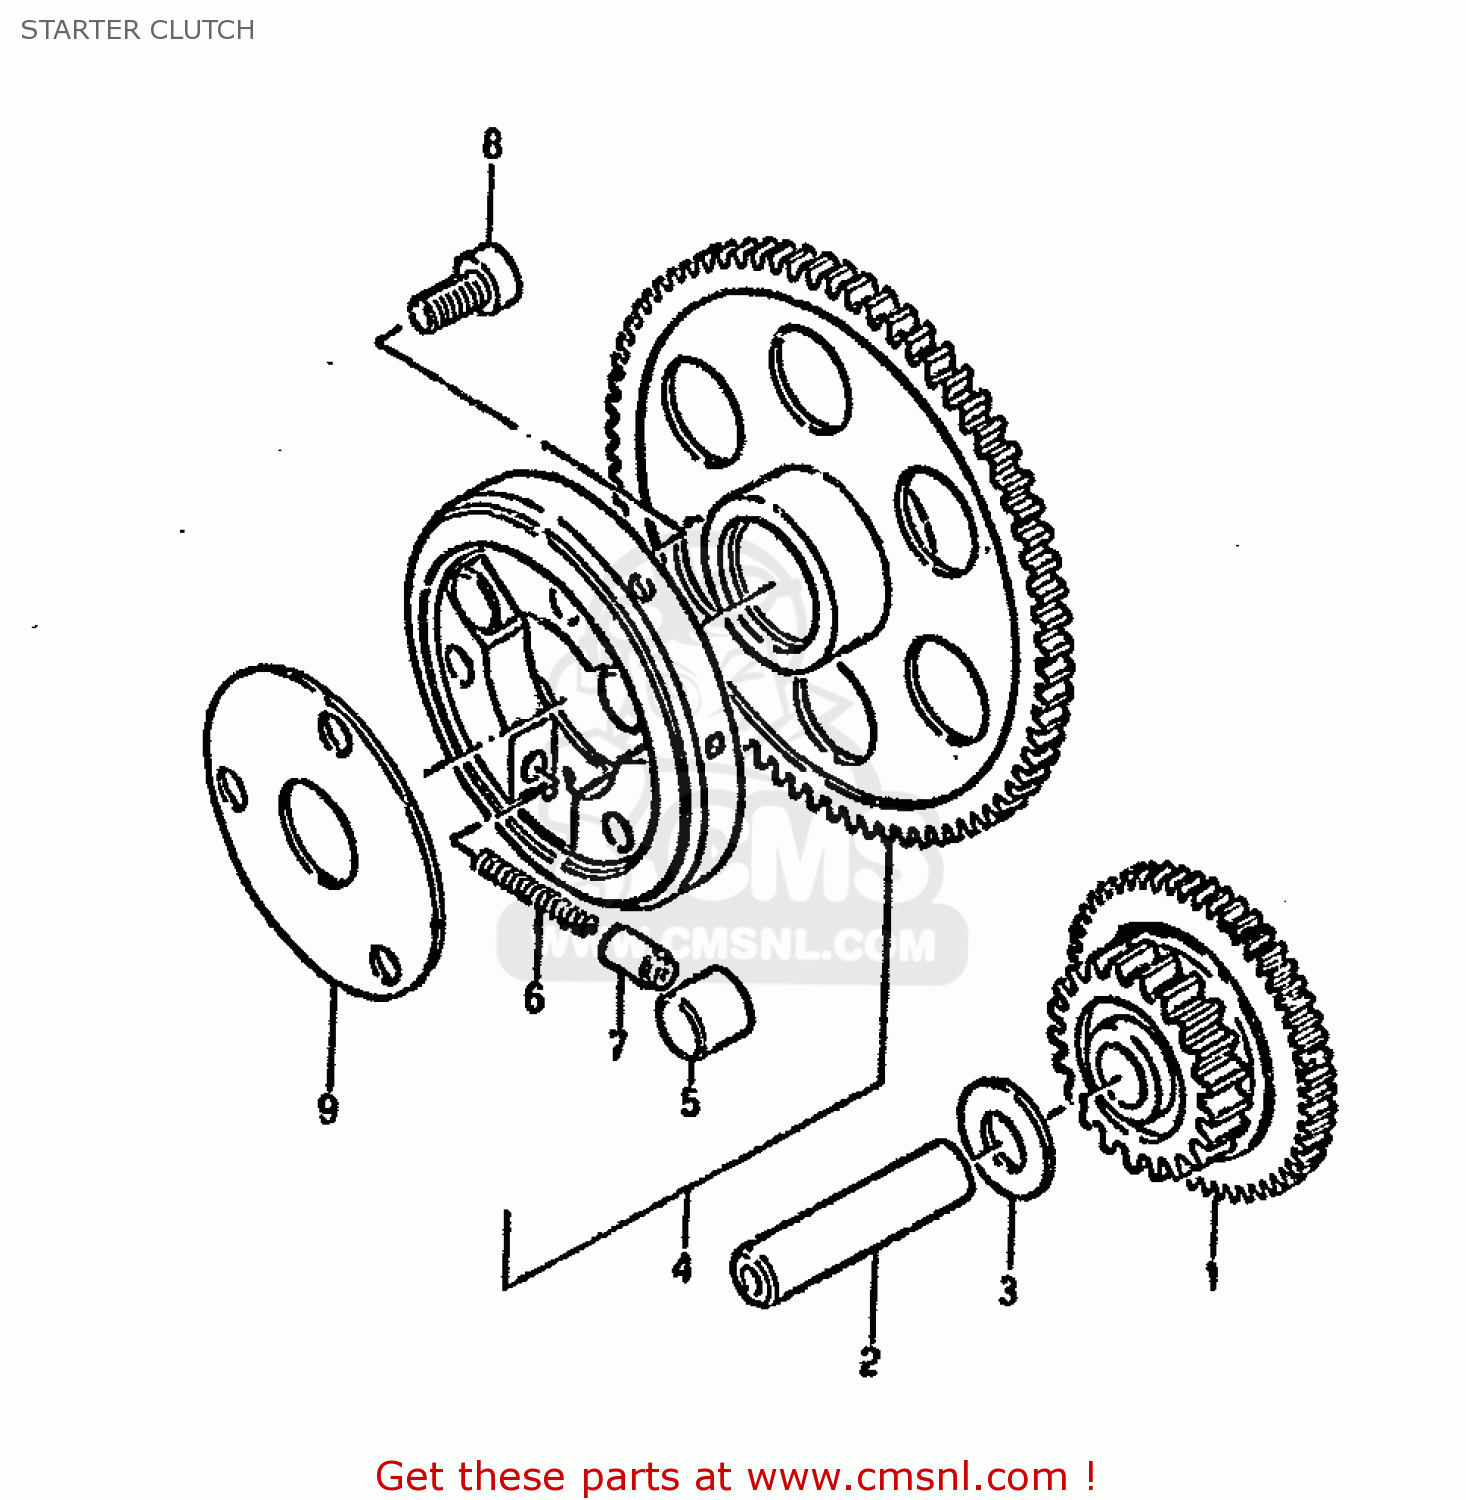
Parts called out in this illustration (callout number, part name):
1	GEAR,STARTER IDLE
2	PIN(7.4X13X56)
3	WASHER
4	CLUTCH SET,STARTER
5	ROLLER(15X13)
6	SPRING
7	PIECE,PUSH
8	BOLT
9	SHIM,STARTER CLUTCH HUB
